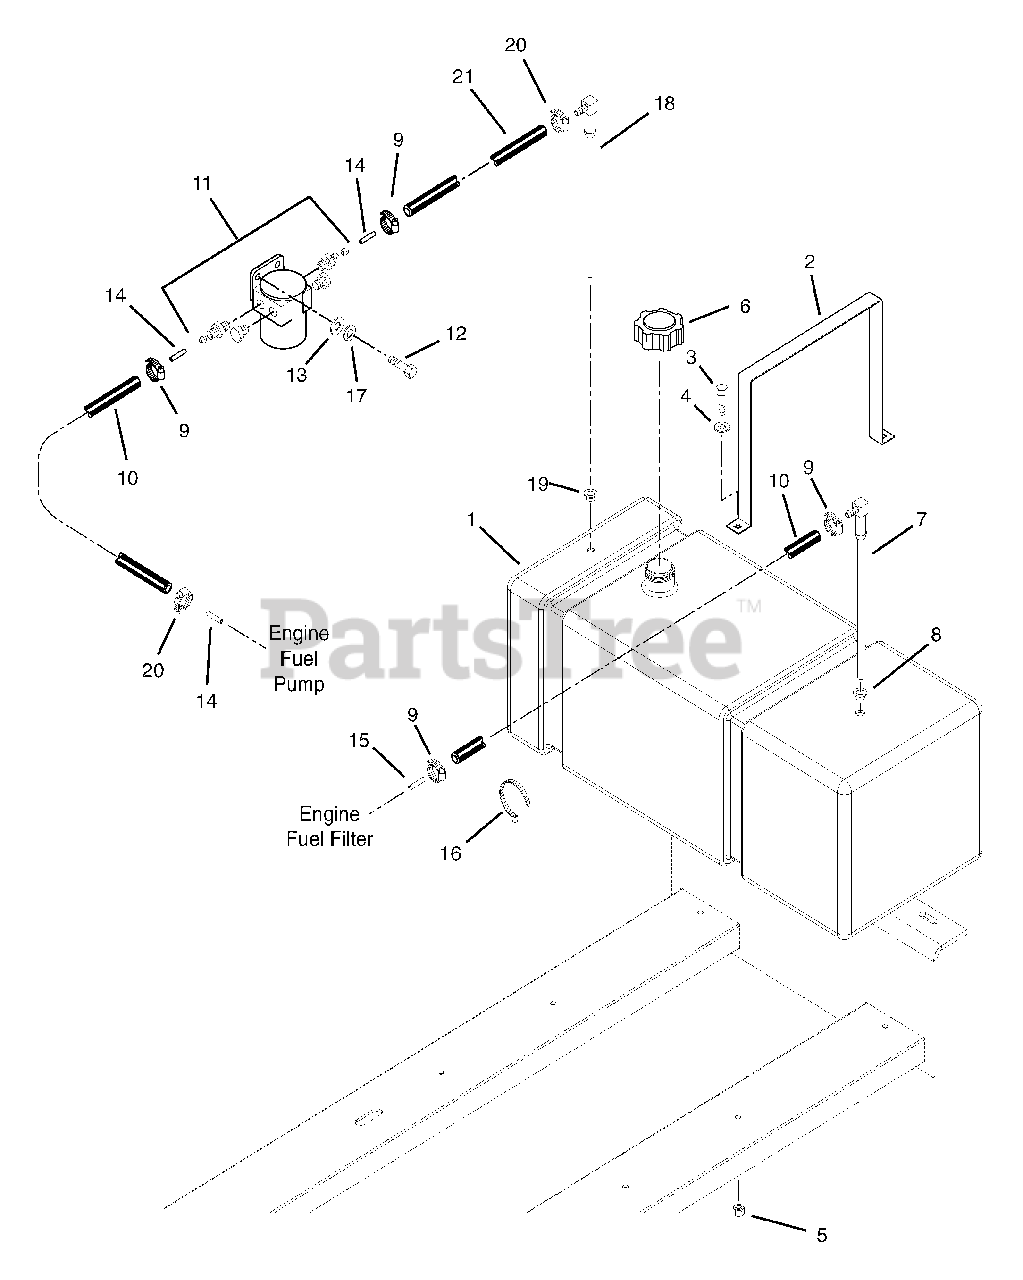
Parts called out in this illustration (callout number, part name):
1	Fuel Tank
2	Fuel Tank Strap
3	Bolt-Hex .375-16 x 1.75 Grade 5
4	Washer-Flat-Steel .438 x 1.00 x .083
5	Nut-Locking-Center .38-16
6	Cap, Fuel Tank
7	Fitting, Tank
8	Bushing
9	Clamp-Hose
10	Gas Line-Bulk
11	Fuel-Pre Filter-Perkins
12	Bolt-Hex .31-18 x 1.25 Grade 5
13	Washer-Flat-Steel .38 x .875 x .083
14	Tubing 5/16" OD x .028 Wall
15	Tubing 1/4" OD x .028 Wall
16	Cable Tie
17	Washer-Lock .31 x .078
18	Fitting, Tank
19	Bushing, Fuel Line Fitting
20	Clamp-Hose
20	Clamp-Hose Worm .44/.78 x .53
21	Gas Line-Bulk 1/4" I.D.
21	Hose-Fuel Line 3/8 in I.D.
